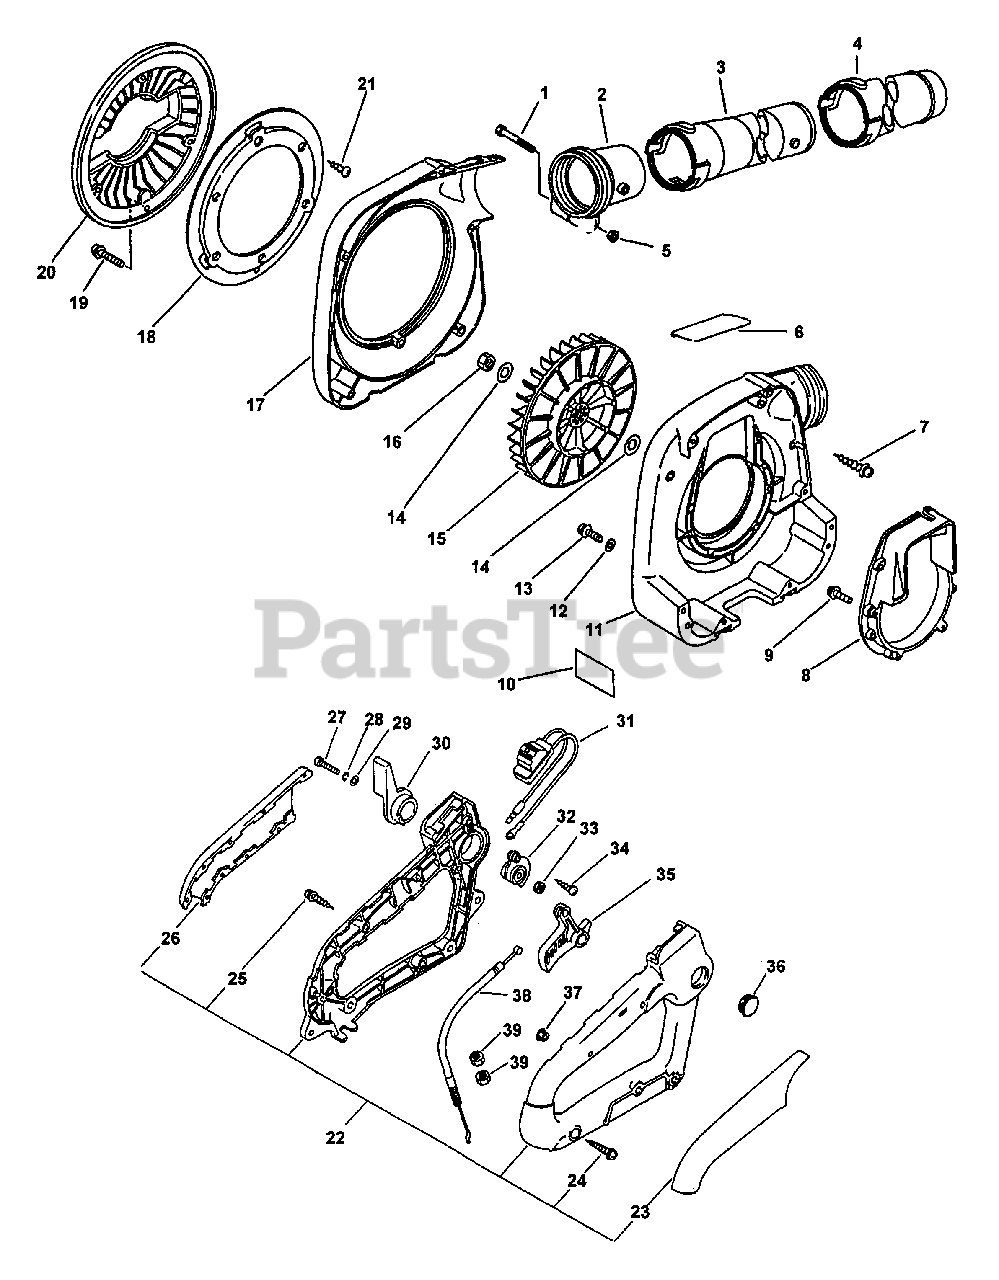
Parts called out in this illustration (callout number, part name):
1	SCREW - 5X60
2	ADAPTER, TUBE
3	TUBE, BLOWER - STRAIGHT
4	TUBE, BLOWER - NOZZLE
5	NUT - 5 -- FLANGE
6	LABEL - NOISE
7	SCREW - 5X30
8	BRACKET, ENGINE
9	SCREW - 4X18
10	LABEL - CAUTION
11	COVER, FAN - RIGHT
13	SCREW - 4X22
14	WASHER - 8
15	FAN
17	COVER, FAN - LEFT
18	BASE, GRID
19	SCREW - 5X16
20	GUARD, DEBRIS
21	SCREW - 4X10
22	HANDLE SET - REAR
23	GRIP, HANDLE - RIGHT
24	SCREW - 5X35
25	SCREW - 4X22
26	GRIP, HANDLE - LEFT
27	SCREW - 6X20
28	LOCKWASHER - 5
29	WASHER - 6
30	CONTROL, THROTTLE
31	IGNITION SWITCH ASSY
32	BRACKET, THROTTLE
33	LOCKNUT - 6
34	SCREW - 4X10
35	TRIGGER, THROTTLE
37	NUT - 5 -- FLANGE
38	CABLE, THROTTLE
